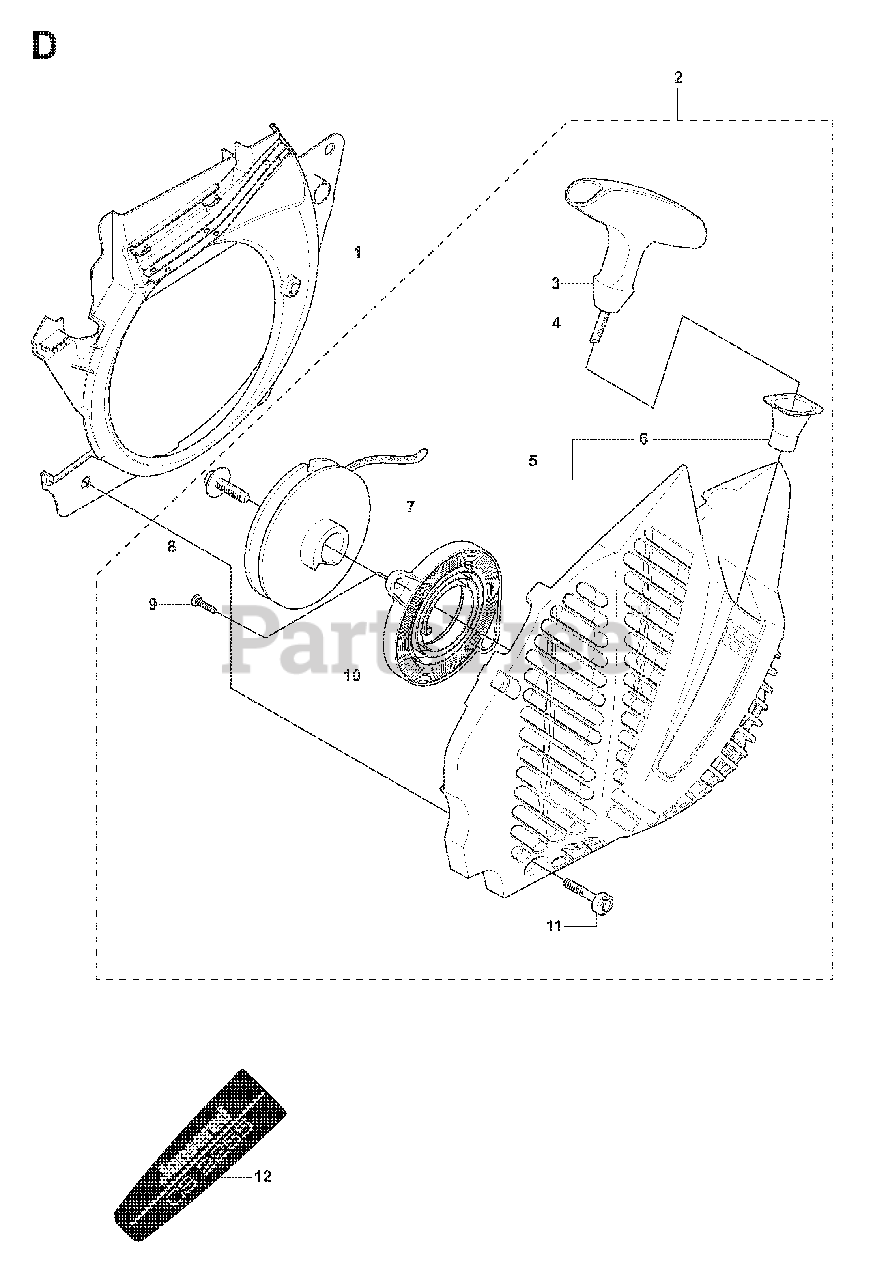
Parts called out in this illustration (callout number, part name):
1	AIR CONDUCTOR
2	STARTER ASSY
3	STARTER HANDLE
4	STARTER ROPE
5	STARTER HOUSING
7	PULLEY
10	RETURN SPRING
